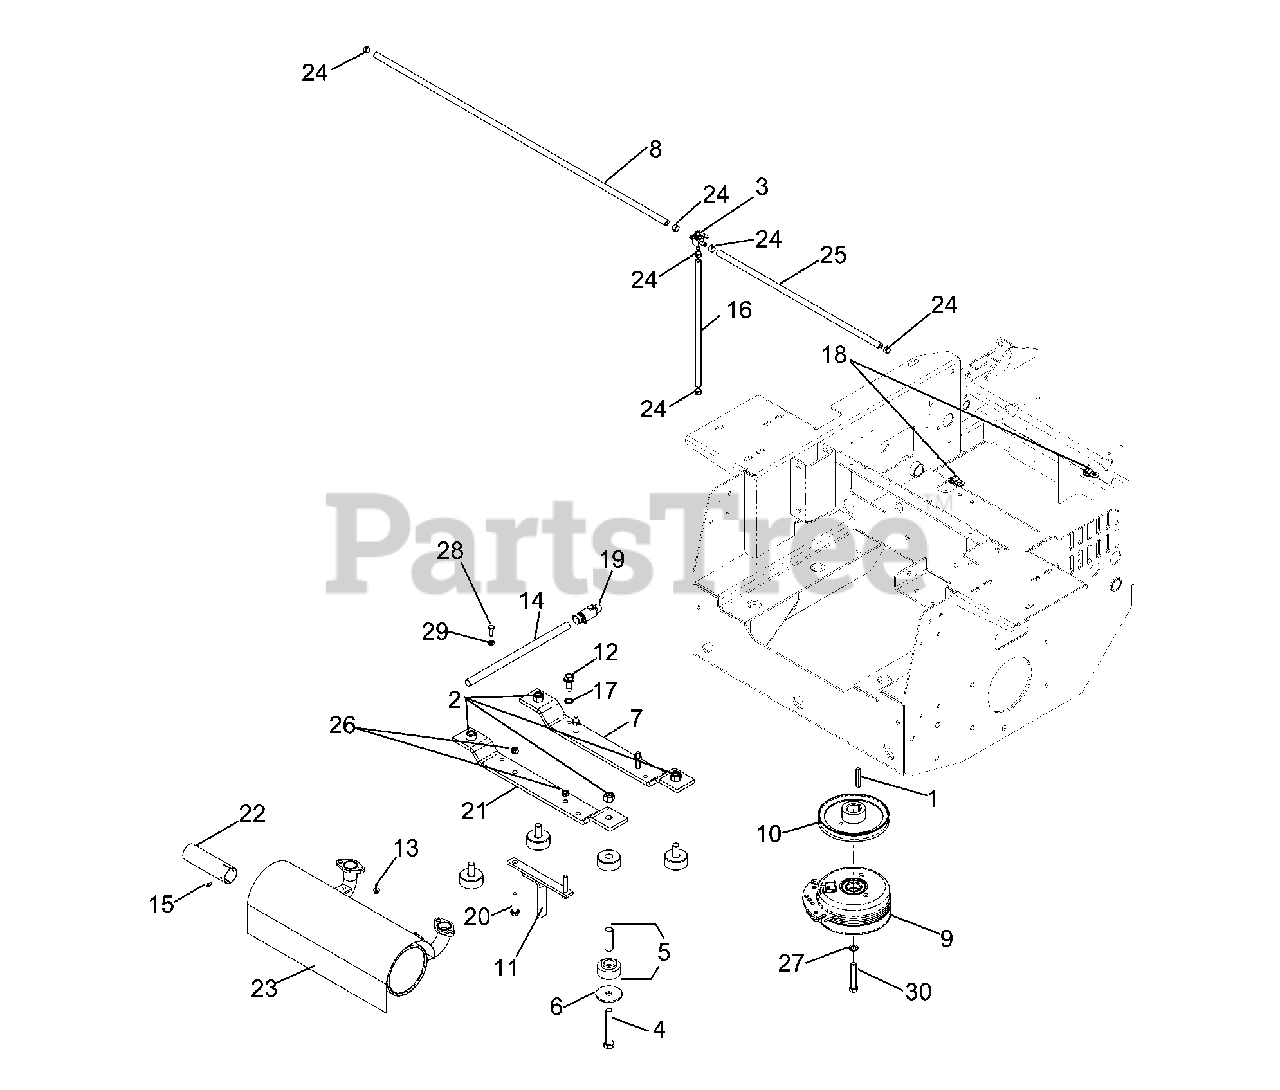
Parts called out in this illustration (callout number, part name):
1	KEY 1/4" SQ X 1 7/8"
2	NUT 1/2-13 HEX NYLOC ZD
3	FUEL VALVE
4	HCS 1/2C X 3 1/4
5	ISOLATORS
6	ISOLATOR WASHER
7	ENGINE MOUNT
8	HOSE 35"
9	ELECTRIC CLUTCH W/CABLE
11	CLUTCH TIE DOWN
12	BOLT 3/8-16 X 1.0
13	SCREW- 1/4-20 X 5/8
14	OIL DRAIN HOSE
15	SCR #8 X 1/2 PHIL HD DRILL BLK
16	FUEL LINE 13"
17	WASHER 3/8 EXT STAR ZD
18	DOUBLE TUBE CLAMP
19	OIL DRAIN FITTING
20	HCS 5/16-18 X 1-3/4 SERATED
21	STRAP, ISO, REAR
22	TUBE, EXTENSION, MUFFLER
23	MUFFLER
24	HOSE CLAMP
25	FUEL LINE
26	NUT 5/16C CENTERLOCK
27	WASHER 7/16 LOCK
28	HCS 1/4C X 3/4 HCS
29	NUT 1/4C CENTER LOCK
30	BOLT 7/16F X 2 1/2
